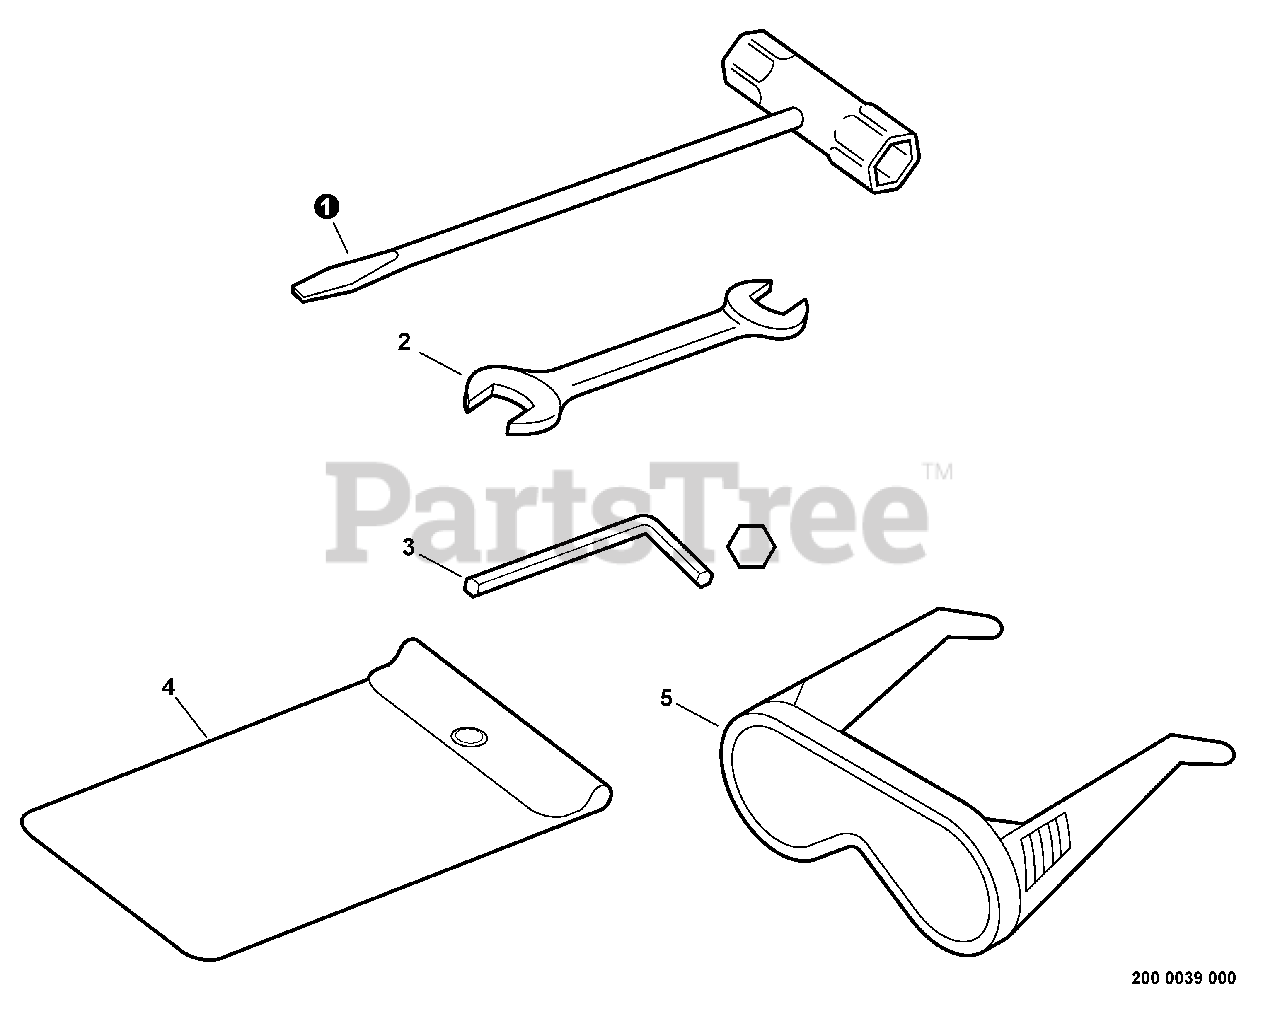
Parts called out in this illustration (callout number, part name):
1	T-WRENCH 17x-19 L200
2	SPANNER 8×10
3	WRENCH, ALLEN 4 MM
4	BAG, TOOL
5	GLASSES, SAFETY
